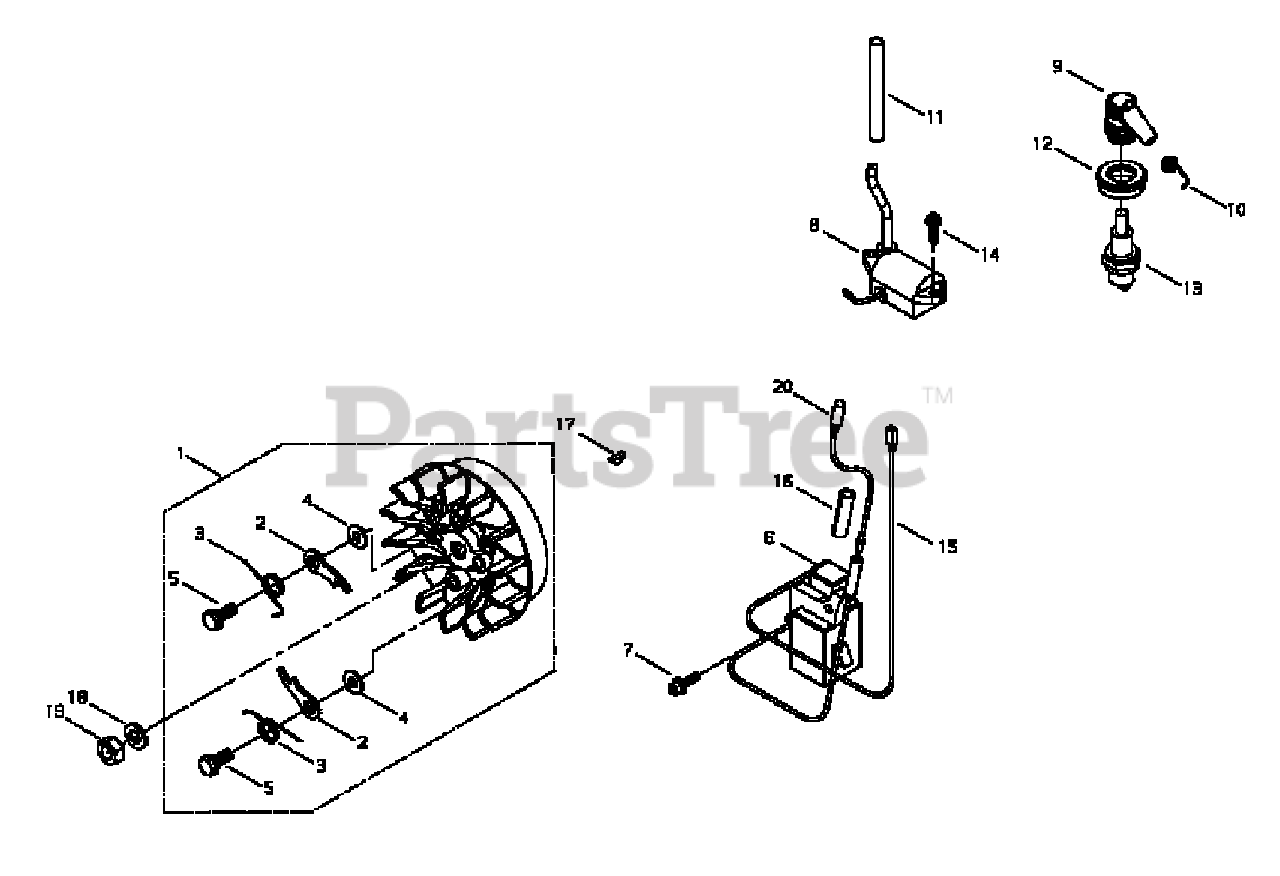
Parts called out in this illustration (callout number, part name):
1	FLYWHEEL
2	PAWL, STARTER
3	SPRING, RETURN
4	WASHER - 6
5	BOLT
6	COIL, IGNITION
7	SCREW - 4X20
8	COIL, IGNITION
9	CAP, SPARK PLUG
10	TERMINAL, SPARK PLUG CAP
12	COVER, DUST
13	SPARK PLUG -- BPMR-7A
14	SCREW - 4X16
16	TUBE
17	KEY - 3X10
18	LOCKWASHER - 8
